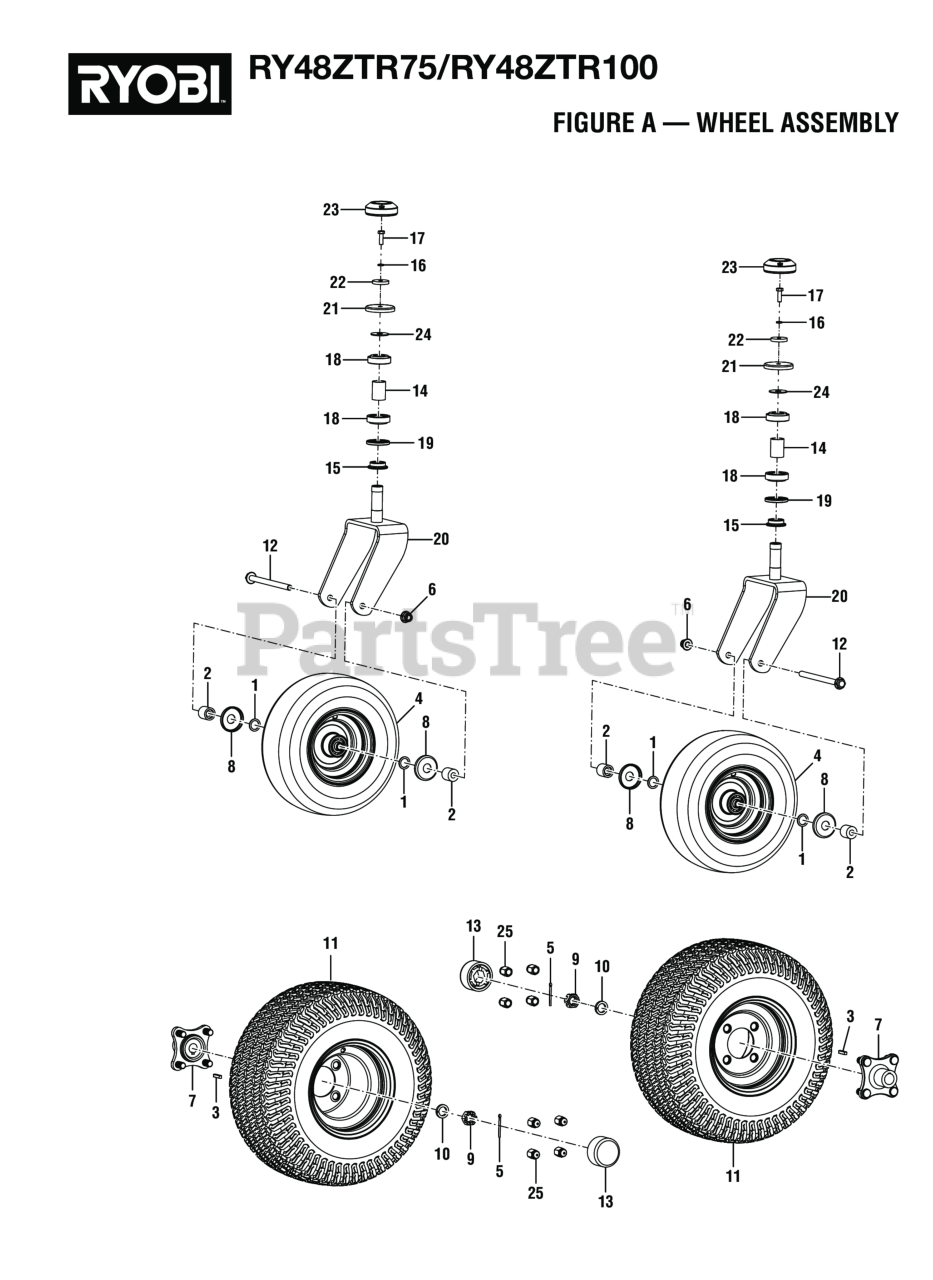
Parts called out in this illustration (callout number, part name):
1	Washer (OD28 x ID20.5 x 2t)
2	Caster Wheel Spacer
3	Key (6 mm x 6 mm x 30 mm)
4	Caster Wheel
5	Drive Shaft Cotter Pin
6	Flange Nut (M12)
7	Wheel Hub
8	Front Wheel Bearing Cover
9	Castle Nut (M20)
10	Lock Spring Washer (20.6 x 30.6 x 4.8t)
11	Rear Wheel Assembly
12	Flange Bolt (M12 x 170 mm, Hex Hd.)
13	Wheel Hub Cover
14	Bearing Assembly Spacer
15	Bearing Assembly Base
16	Lock Washer (OD9.8 x ID8.5 x 5t)
17	Bolt (M8 x 25 mm)
18	Roller Bearing (ID 25 mm x OD 52 mm)
19	Rubber Seal
20	Caster Fork
21	Bearing Assembly Cap
22	Fender Washer (OD37 x ID8.4 x 6t)
23	Caster Fork Cover
24	Fender Washer (OD40 x ID12.5 x 2t)
25	Acorn Nut (M14)
